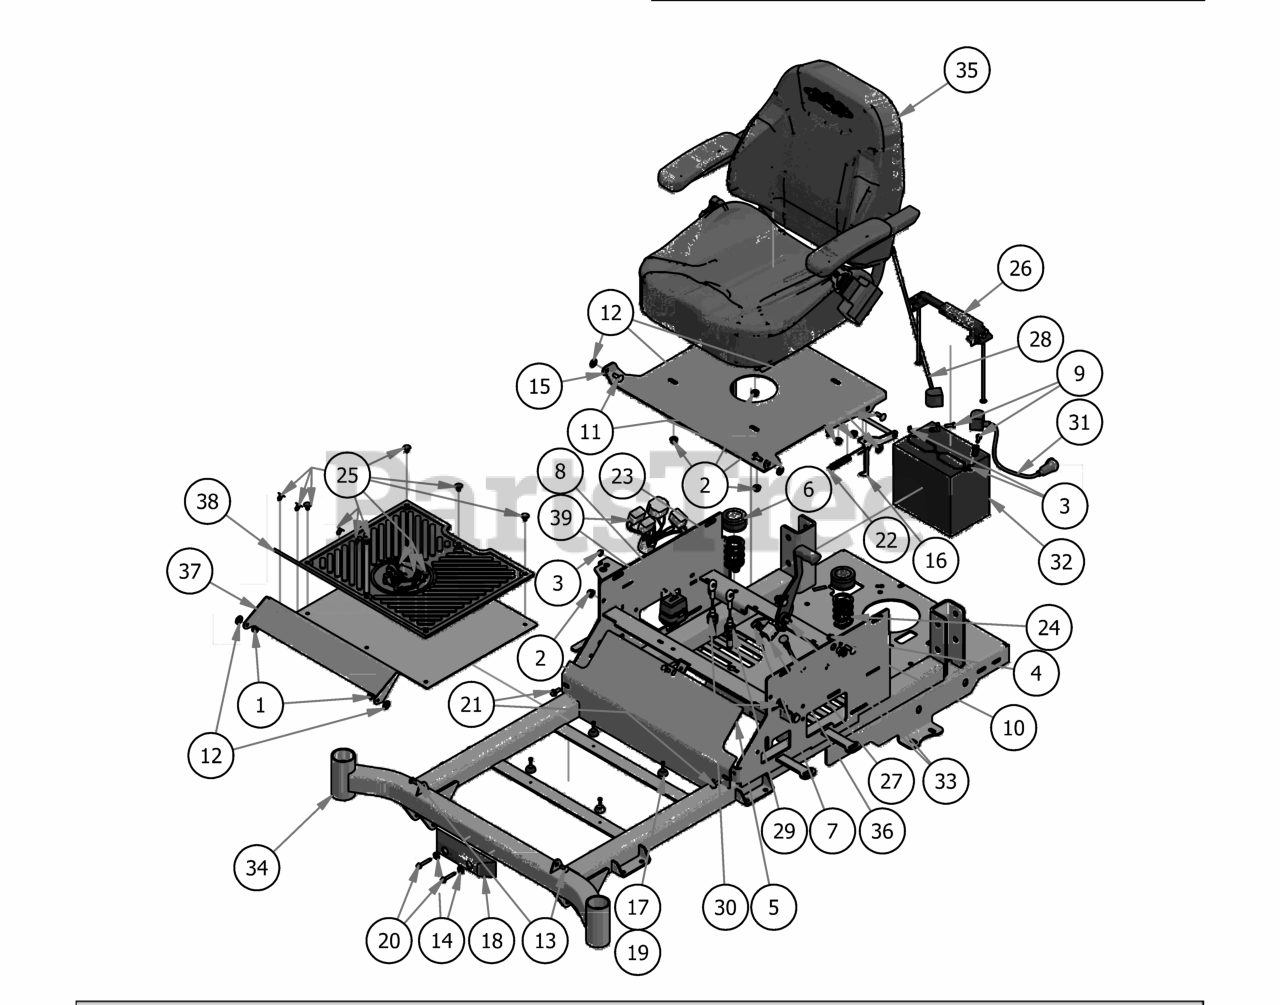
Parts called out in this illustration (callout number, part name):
1	1/4-20 Nylon Insert flange Nut
2	5/16" Nylon Flange Nut
3	1/4-20 Hex Flange Nuts Zinc w/Serrations
4	5/16" Flange Nut
5	2017 ZT Cooler Cover
6	Seat Spring Cap Cover
7	12-24x 1/2 HWH Bolt
8	1/4" x 1/2" BS C/S 18-8 SS
9	1/4" x 3/4" Hex Bolt
10	5/16" x 1" Carriage Bolt
11	5/16" x 7/8" Carriage Bolt
12	.360 ID Plastic Washer
13	1/4" x 3/4" Carriage Bolt
14	5/16" Flat Washer
15	Seat Plate 2016
16	Seat Latch Rod Assembly
17	Button Bumper
18	8" Rubber Bumper
19	#10 x 1/2" Self Tapping Screw
20	1/4" x 1 1/2" Self Tapping Screw
21	5/16 x 3/4 washer head type F screw
22	Brake Spring
23	Seat Spring Assembly
24	Seat Spring Assembly w/Cable
25	5/8" Christmas Tree Fastener
26	Hold Down Assembly
28	24" Black Ground Cable
29	Brake Cable,18.5"
30	Brake Cable, 24.5"
31	24" Red Battery Cable
33	2017 ZT Brake Handle Assembly
34	2018 Compact Outlaw Frame
35	2019 Maverick Seat
36	Safety Switch
37	MZ/ZT 2017 Floorboard
38	2017 MZ/ZT Floor Mat
39	Wiring Harness
